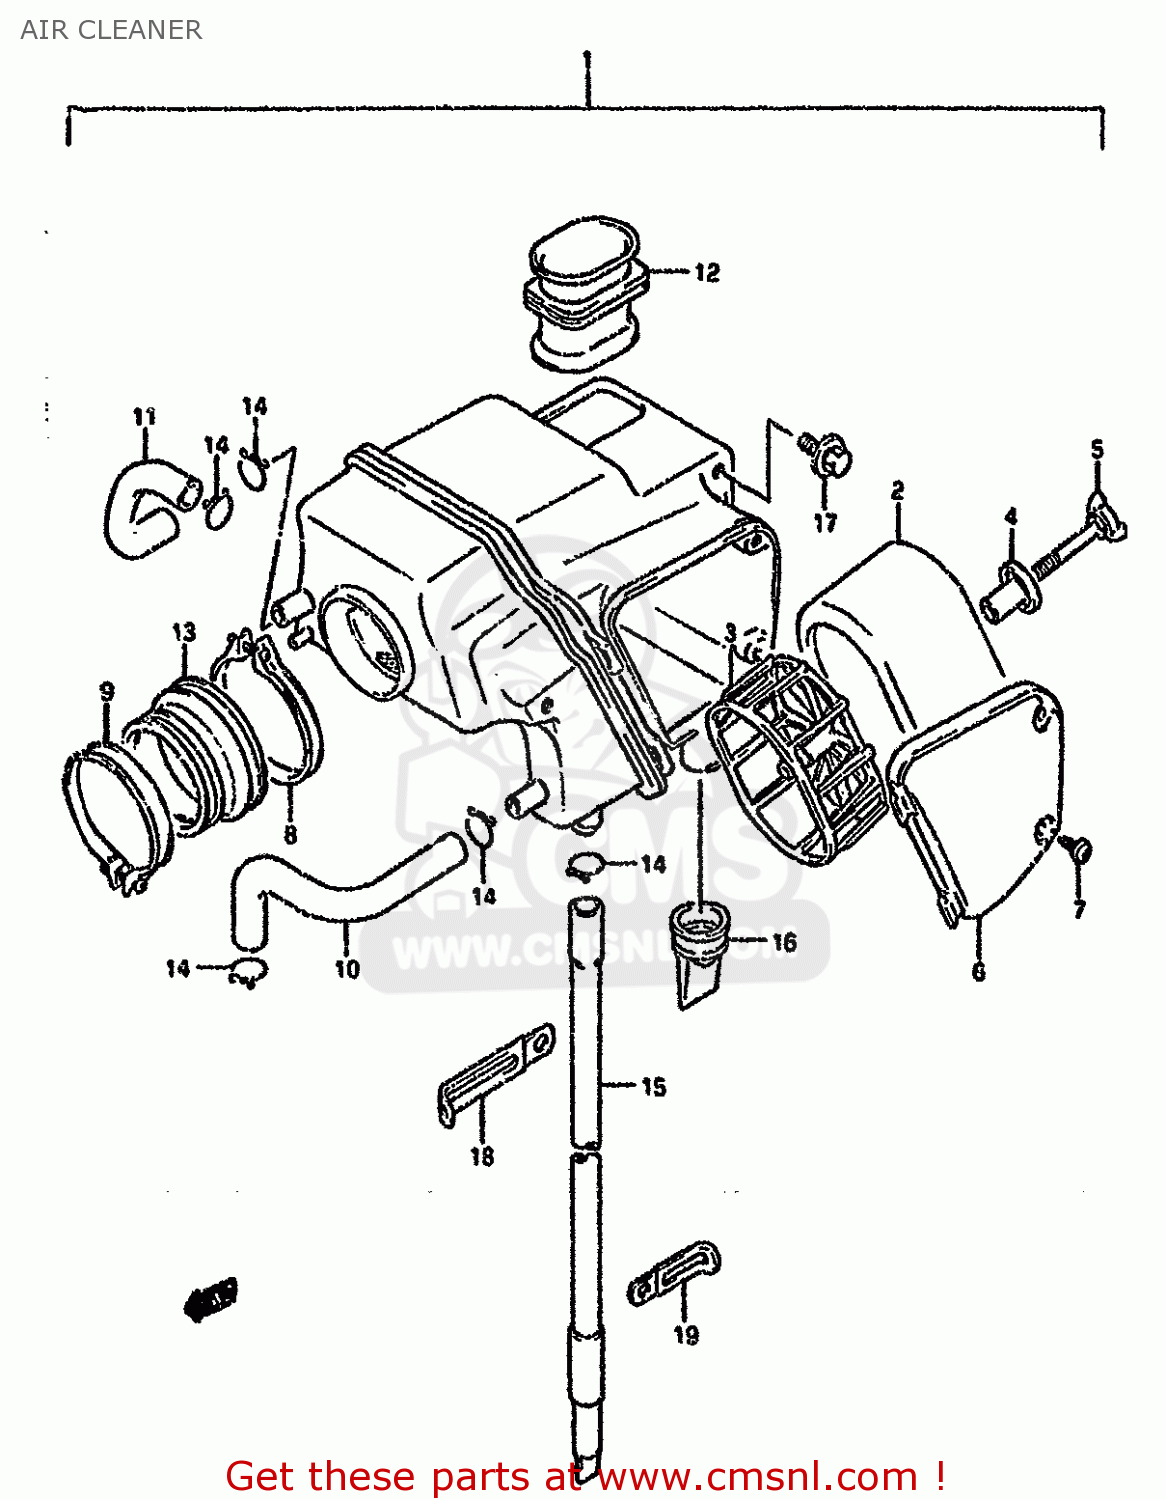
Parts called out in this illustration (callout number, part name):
1	CLEANER ASSY,AIR
2	FILTER
3	HOLDER,FILTER
4	SPACER
5	BOLT,WING
6	CAP,AIR CLEANER
7	SCREW
8	CLAMP
9	CLAMP
10	TUBE,BREATHER
11	TUBE,CONNECTING
12	TUBE,INLET
13	TUBE,OUTLET
14	CLIP
15	TUBE,DRAIN
16	CAP,DRAIN
17	BOLT(6X14)
18	CLAMP(L:65)
19	CLAMP
